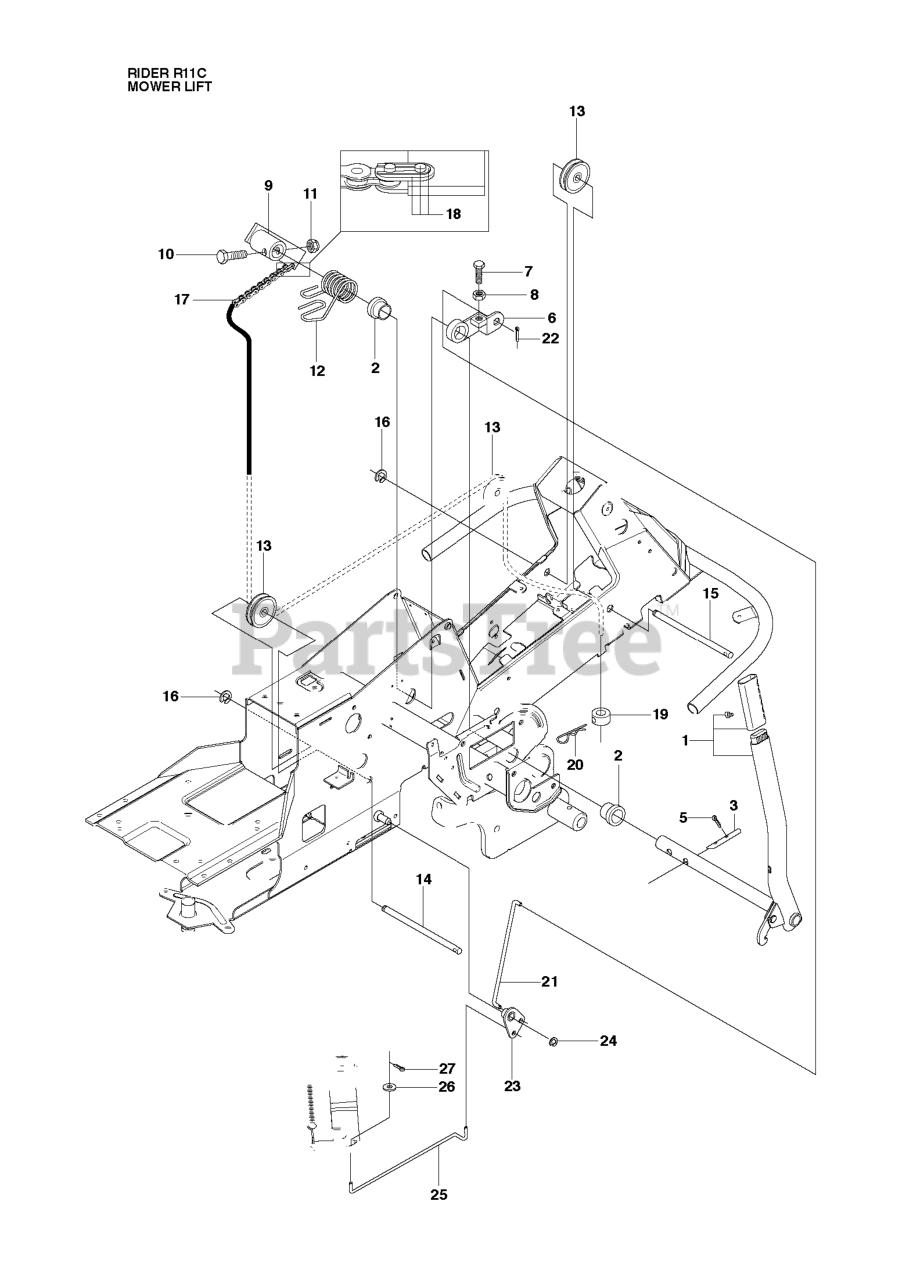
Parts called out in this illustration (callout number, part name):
1	LIFTING LEVER ASSY
2	BEARING FLANGE
6	LEVER CLUTCH
8	NUT
9	LIFTING ARM
21	CONNECTION ROD
24	RETAINING RING
25	CONNECTION ROD
